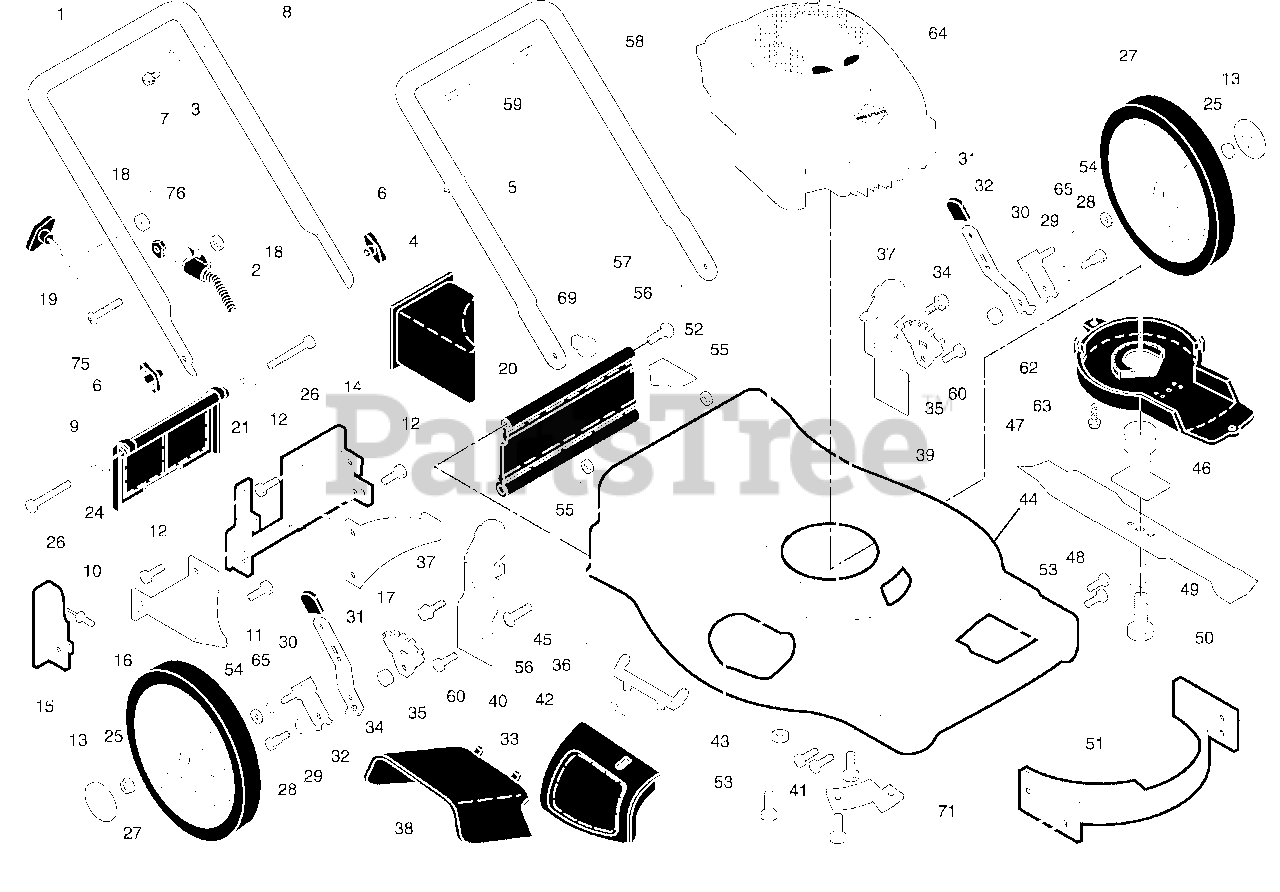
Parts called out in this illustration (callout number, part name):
1	Upper Handle
2	Key Start Switch
3	Bracket, Upstop
4	Mulcher Plug
5	Wire Tie
6	Handle Knob
7	Screw
8	Control Bar
9	Rear Door Assembly
10	Pop Rivet
11	Screw, Self-Tapping #10-24 x 5/8
12	Screw, Hex Hex Head, Sems 1/4-20 x 1/2
13	Hubcap
14	Back Plate
15	Side Baffl e
16	Discharge Baffl e
17	Rear Baffl e
18	Keps Locknut 1/4-20
19	Rope Guide
20	Rear Skirt
21	Spring, Rear Door, LH
24	Spring, Rear Door, RH
25	Nut, Hex, Flanged
26	Bolt, Rear Door
27	Wheel & Tire Assembly, Rear
28	Bolt, Shoulder 3/8-16 x 1
29	Washer, Curved, Cylindrical
30	Axle Arm Assembly
31	Selector Knob
32	Selector Spring
33	Mulcher Door
34	Spacer
35	Wheel Adjusting Bracket
36	Hinge Bracket Assembly
37	Screw, Sems, Thread Cutting 5/16-18 x 3/4
38	Discharge Defl ector
39	Handle Bracket Assembly, LH
40	Handle Bracket Assembly, RH
41	Screw, Hex Head, Threaded, Rolled 3/8-16 x 1-1/8
42	Spring, Torsion
43	Nut, Hex, Nylock
44	Kit, Mower Housing
45	Rod, Hinge
46	Blade Adapter / Pulley
47	Blade, 22"
48	Washer, Hardened
49	Washer, Helical
50	Screw, Machine, Hex Head 3/8-24 x 1-3/8 Grade 8
51	Kit, Front Baffle
52	Danger Decal
53	Screw, Serrated, TT 1/4-20
54	Washer, Flat
55	Nut, Hex 3/8-16
56	Hinge Screw 1/4-20 x 1-1/4
57	Hairpin Cotter
58	Lower Handle
59	Handle Bolt
60	Bolt, Hex Head 3/8-16 x 3/4
62	Debris Shield
63	Screw, Debris Shield
65	O-Ring
69	Clip, Cable
71	Mounting Bracket, Debris Shield
75	Screw
76	Key
76	Operator's Manual, English
76	Operator's Manual, French
76	Repair Parts Manual
